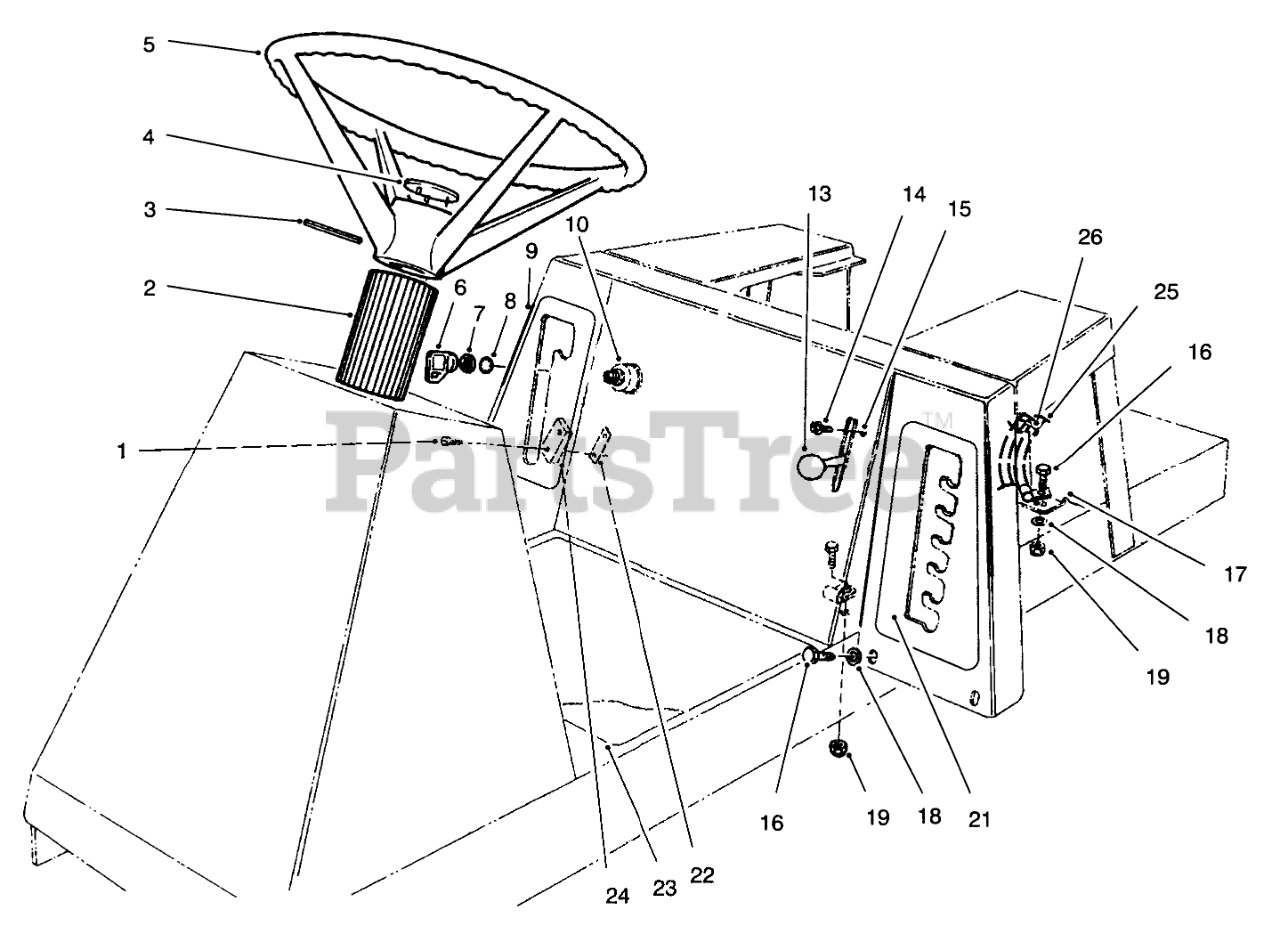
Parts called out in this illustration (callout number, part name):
1	SCREW-HH
2	COVER-STEERING SHAFT
3	PIN-ROLL
4	INSERT - STRG WHL F/W
5	Assy.-Wheel, Steering (Incl. Ref. #4)
6	KEY-IGNITION
7	NUT-HH
8	WASHER-TOOTH, INTERNAL
9	DECAL - DECK ENGAGE
10	Switch-Ignition (Incl. Ref. #6-8)
13	KNOB-CONTROL
14	SCREW-HWHTF
15	Control-Throttle (Incl. Ref. #13)
16	SCREW-HH
17	CLIP
18	WASHER-PLAIN
19	NUT-LOCK, NI
21	DECAL - HOC
22	NUT-SPEED
23	DECAL - INSTRUCTION
24	SWITCH-MICRO
25	WIRE ASM
26	TIE-CABLE
